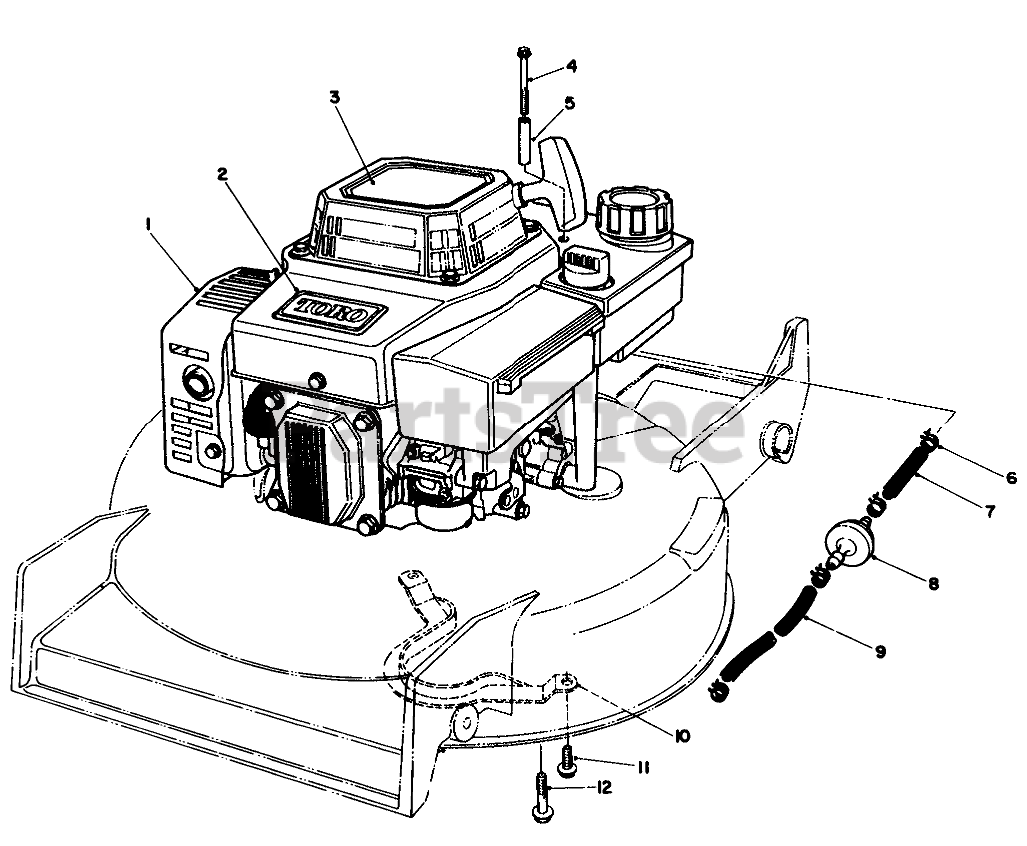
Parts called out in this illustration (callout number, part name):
1	Engine
2	TORO LOGO PLT
3	DECAL-HV INT'L
4	THRD FORMING SCREW
5	TUBULAR SPACER
6	CLAMP-FUEL LINE
7	LINE-GAS
8	FILTER-FUEL
9	HOSE-FUEL
10	BBC BELT GUIDE
11	Screw
12	SCREW-HWHTF
